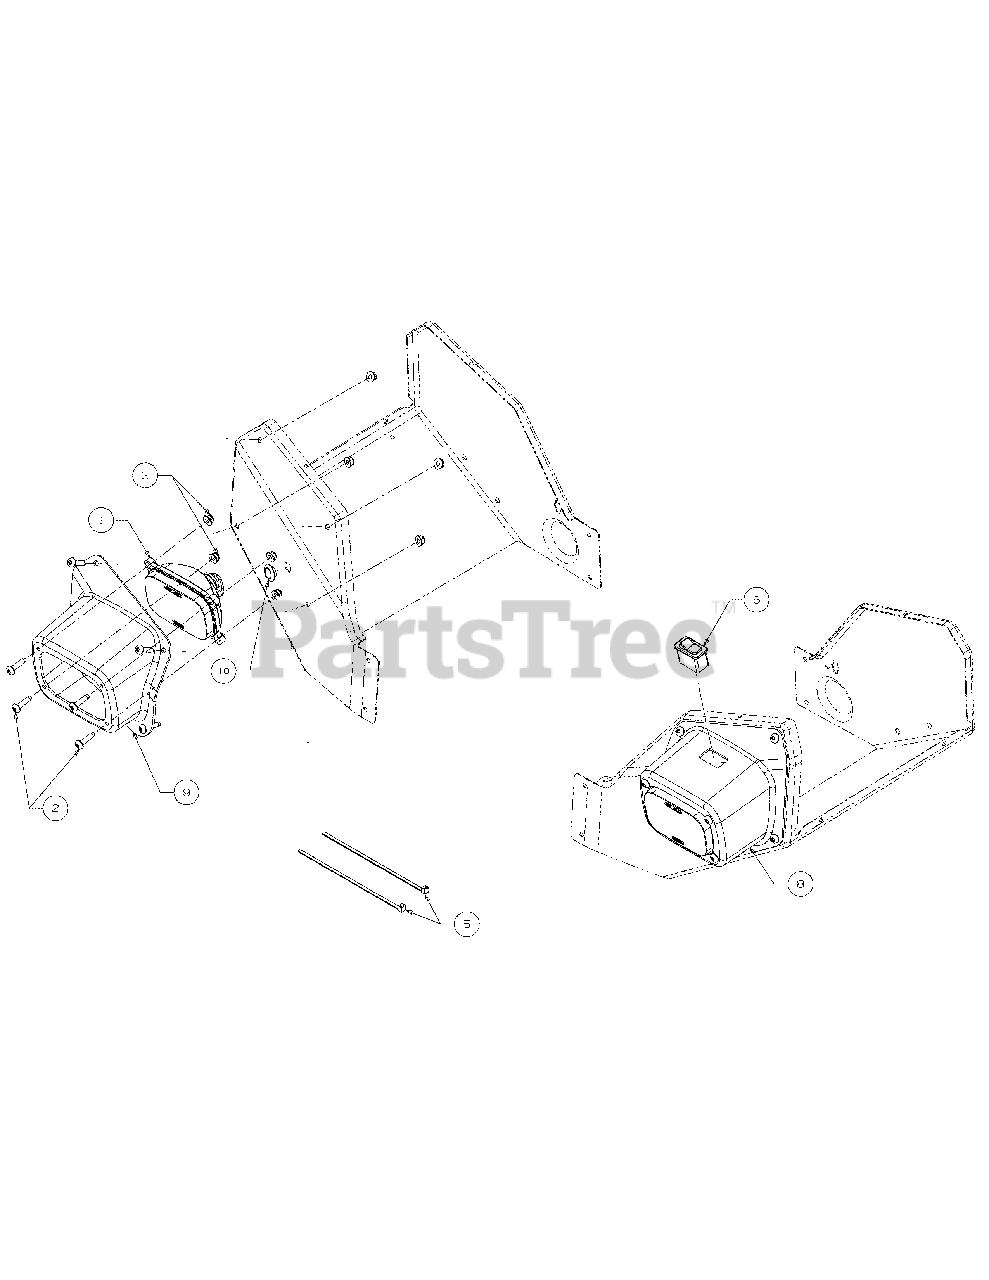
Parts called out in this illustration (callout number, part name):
1	Headlight Assembly
2	Screw, Torx 1/4-20
3	Nut, Nylon 1/4-20
5	Tie, Cable 7"
6	Switch, Light Bar
8	Benzel, Headlight Left
9	Benzel, Headlight Right
